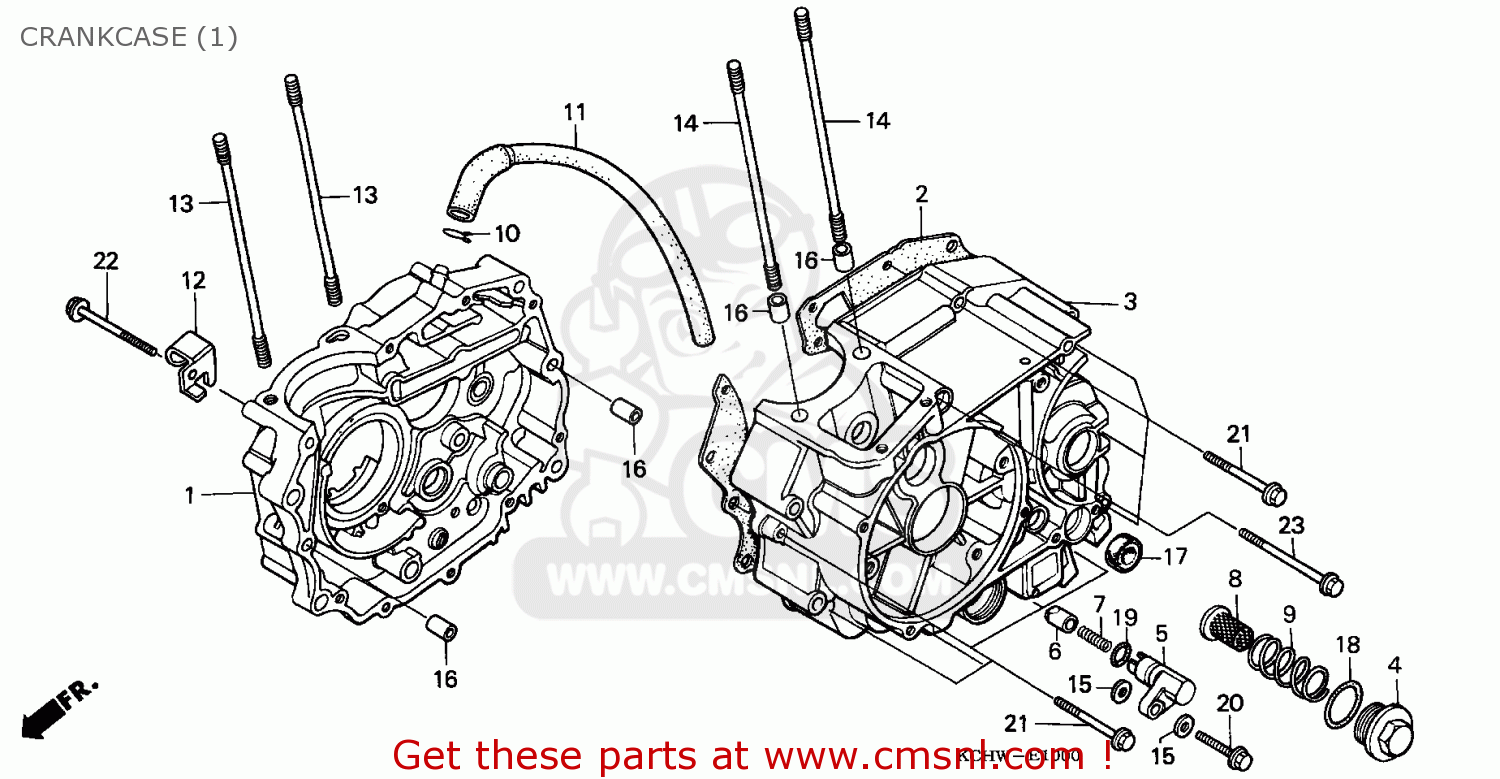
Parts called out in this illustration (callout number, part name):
1	CRANK CASE COMP,R
2	GASKET,CRANK CASE (NAS)
3	CRANK CASE COMP,L
4	CAP,HOLE
5	HOLLDER,PUSH PLUG
6	PLUG,BRG PUSH
7	SPRING,BEARING PU
8	SCREEN,OIL.FILTER
9	SPRING,SCREEN
10	CLIP, OIL DRAIN TUBE
11	TUBE,BREATHER
12	HOLDER,CLUH.WIRE
13	BOLT,CYLIN 8X122
14	BOLT B,CYLIN.STUD
15	WASHER,SEALING 6
16	PIN,DOWEL,10X14
17	OIL SEAL,14X28X7
18	O-RING,35X3
19	O RING,13X2.5
20	BOLT,FLANGE,6X25
21	BOLT,FLANGE,6X50
22	BOLT,FLANGE,6X55
23	BOLT,FLANGE,6X95
